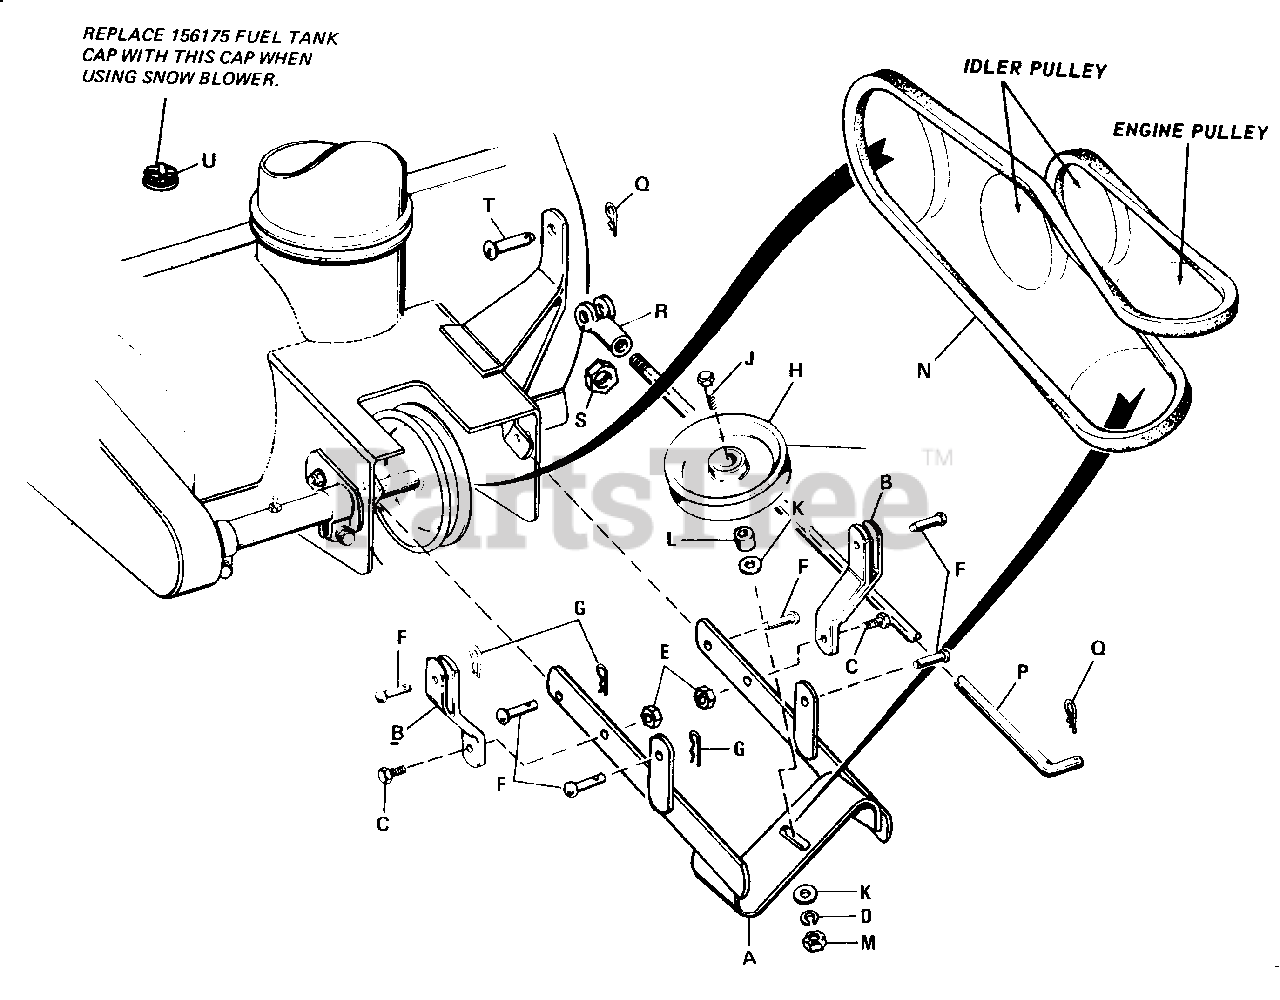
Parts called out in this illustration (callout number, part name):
A	Hitch Assembly
B	Support Arm Assembly
C	Hex Capscrew, 3/8"-16 x 1 lg.
D	Lock Washer, 3/8"
E	Hex. Nut, Full Lock, 3/8"-16
G	Spring Clip
J	Hex. Capscrew, 3/8"-16 x 1-3/4" lg.
K	Plain Washer, 3/8 "
M	Hex. Nut, Full, 3/8"-16
N	"V" Belt
P	Front Lift Rod
Q	Spring Clip
R	Adj. Yoke
S	Hex. Nut, Full, 1/2"-20
U	Cap (Winter) Fuel Tank
